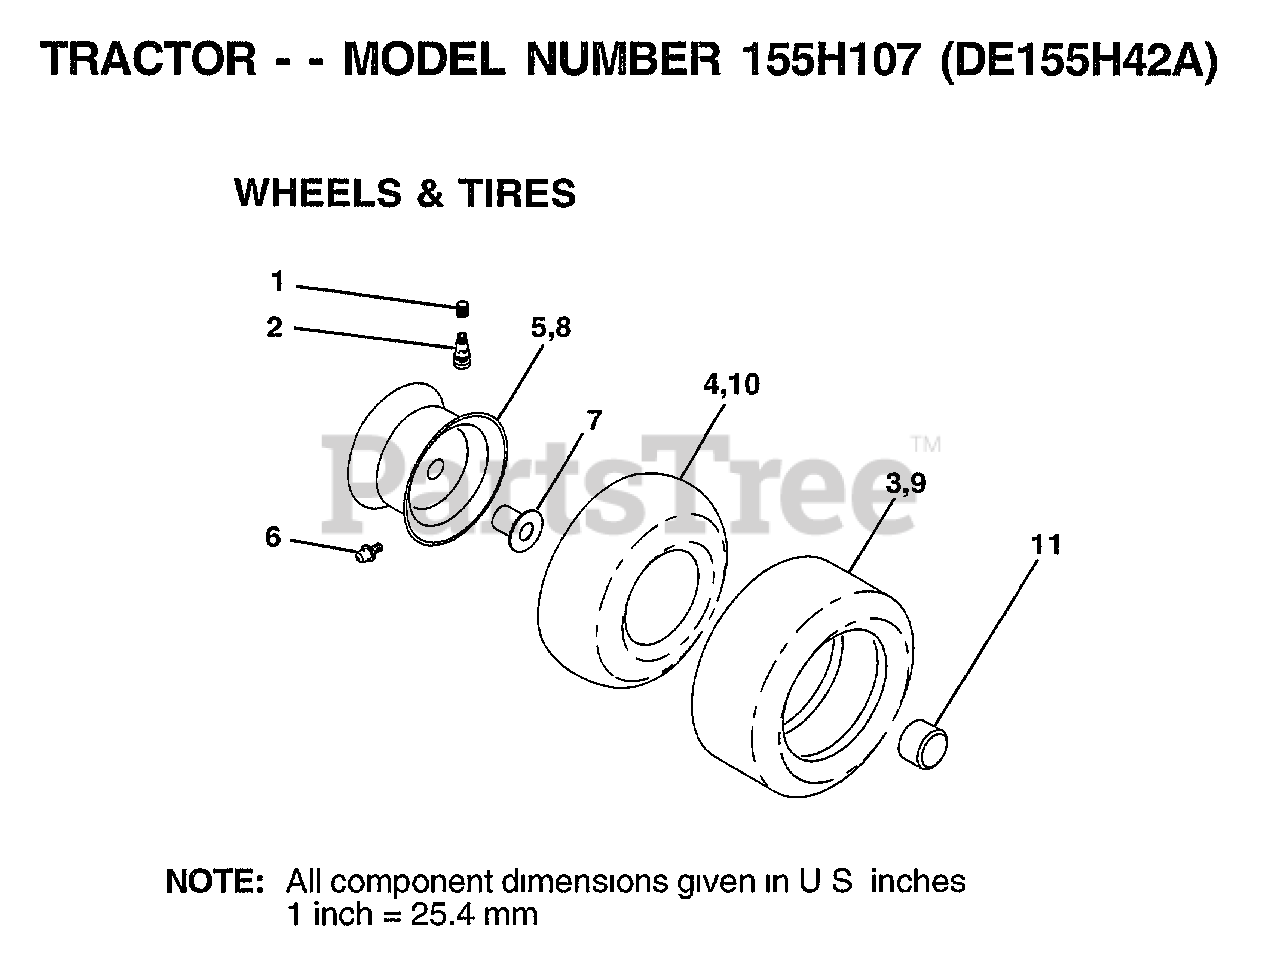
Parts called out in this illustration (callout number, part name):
1	VALVE CAP
2	VALVE STEM LT
4	TUBE.5.3/4.5/6
5	"RIM,FRT T"
6	FITTING LT
7	"FLANGE, BEARING"
8	"RIM 8"""
10	TUBE.18X9.5-8
11	HUB CAP
